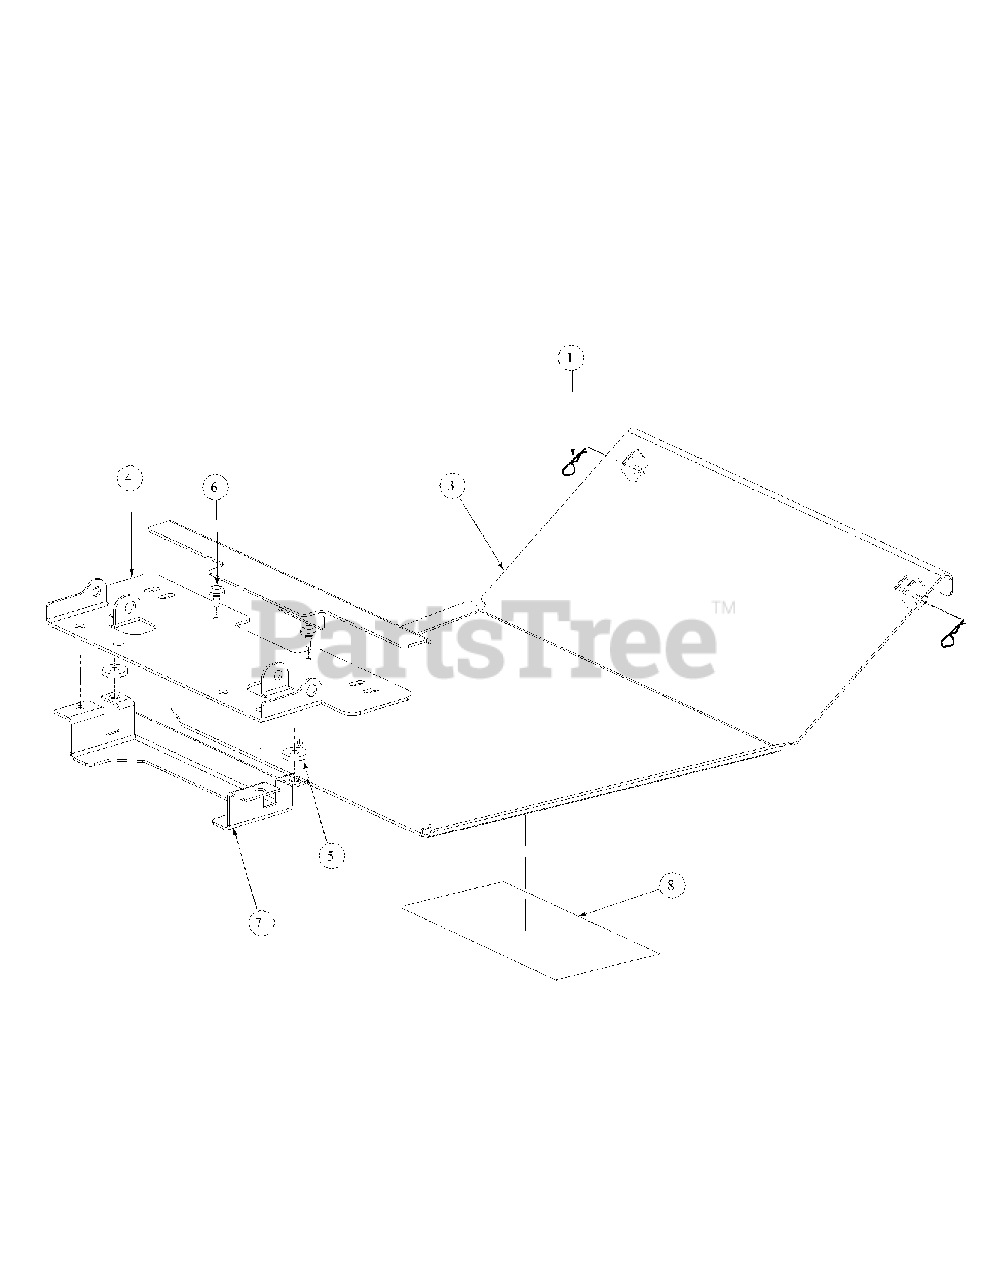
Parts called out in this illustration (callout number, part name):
1	Hair Pin, 3/8-1/2
3	Floor Panel Assembly
5	Washer
6	Rubber Bumper, .62 OD x .22 Thick
7	Support, Seat Bracket
8	Label, Belt Routing and Lubrication
